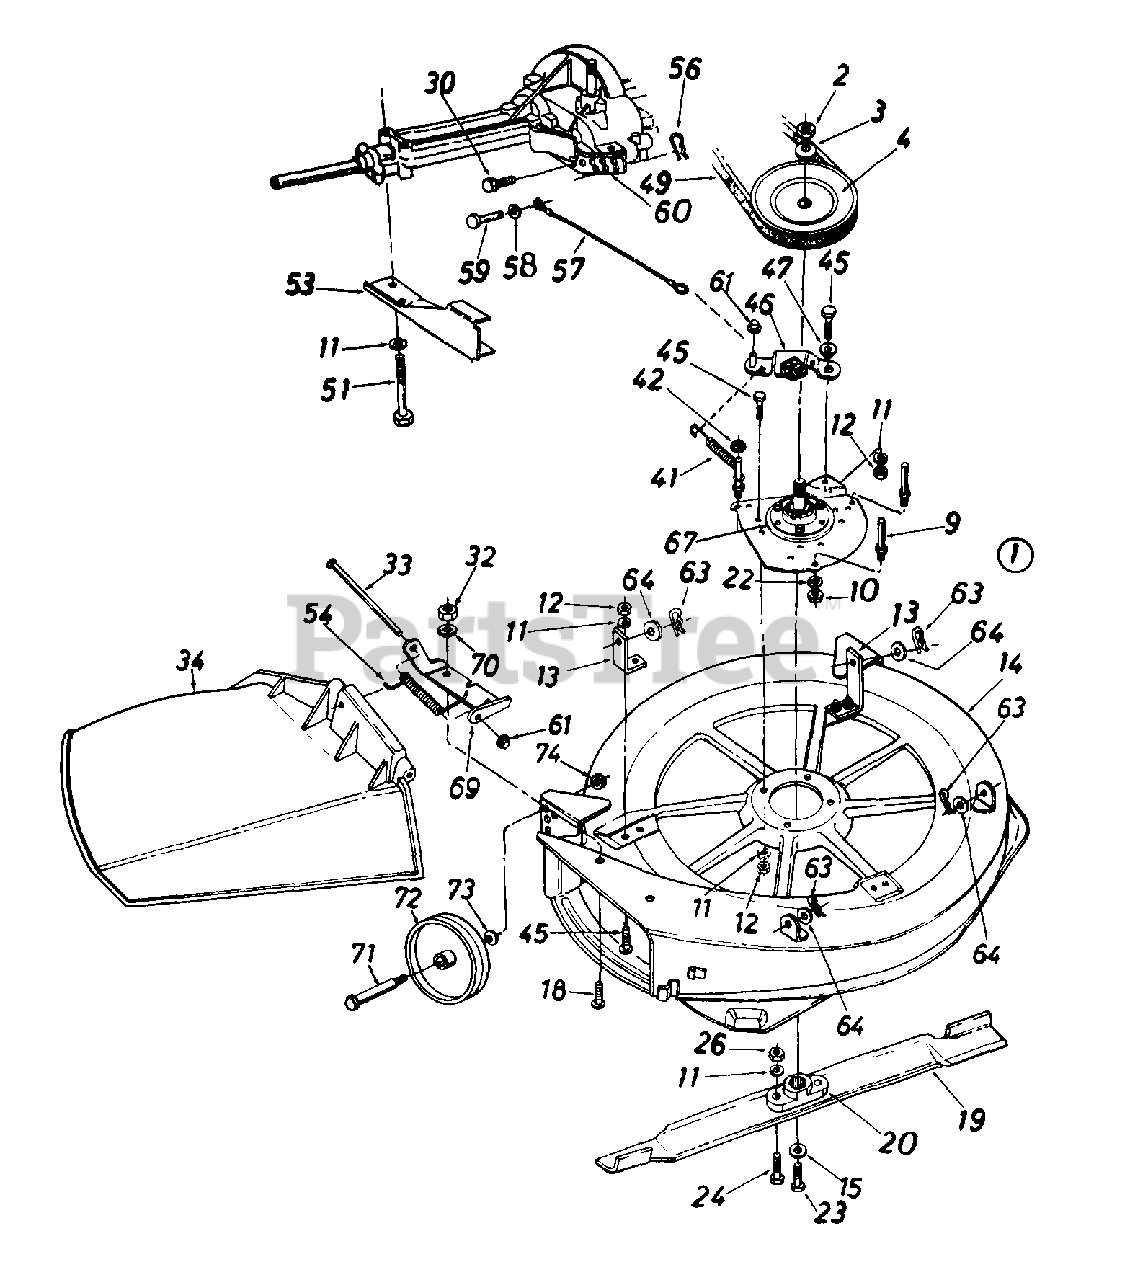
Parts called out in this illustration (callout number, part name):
3	Bell-Wash. .630" I.D. x 1.25"
4	5/8 V-Pulley .75" I.D. x 7"
9	Stud 3/8-16 x 2.75" Lg.
10	Hex Jam Nut 3/8-16 Thd.
11	L-Wash. 5/16" I.D.
12	Hex Nut 5/16-18 Thd.
18	Hex Bolt 1/4-20 x .62" Lg.
19	30" High Lift Blade
20	Blade Adapter
22	L-Wash. 3/8" I.D.
23	Hex Bolt 3/8-24 x 1.0
24	Hex Bolt 5/16-24 x 1.0" Lg.
26	Hex Nut 5/16-24 Thd.
30	Hex Bolt 1/4-20 x .50" Lg
32	Hex Nut 1/4-20 Thd.
33	Hinge Pin
34	Chute Ass'y. Comp.
41	Extension Spring
42	Push Speed Nut
45	Hex Bolt 5/16-18 x .75"
46	Blade Brake Brkt. Ass'y.
47	Shoulder Spacer .500" Dia
49	"V"-Belt
51	Hex Bolt 5/16-18 x 2.75"
56	Int. Cot. Pin 5/16" Dia
57	Brake Cable 9.75" Lg.
58	FI-Wash. .281" I.D. x .50"
59	Clevis Pin 1/4" Dia.
60	Lower Inside Belt Guard
61	Cap Speed Nut 1/4" Rod
63	Int. Cotter Pin 1/2" Dia.
64	Fl-Wash .531" I.D. x .930"
67	Blade Spindle Ass'y. Comp.
69	Hinge Mtg Brkt.
70	Bell-Wash. 1/4" I.D.
71	Shld. Scr. .498" x 1.53" Lg
72	Deck Wheel
73	Bell-Wash. 38" I.D. x 88"
74	Hex L-Nut 3/8-16 Thd.
